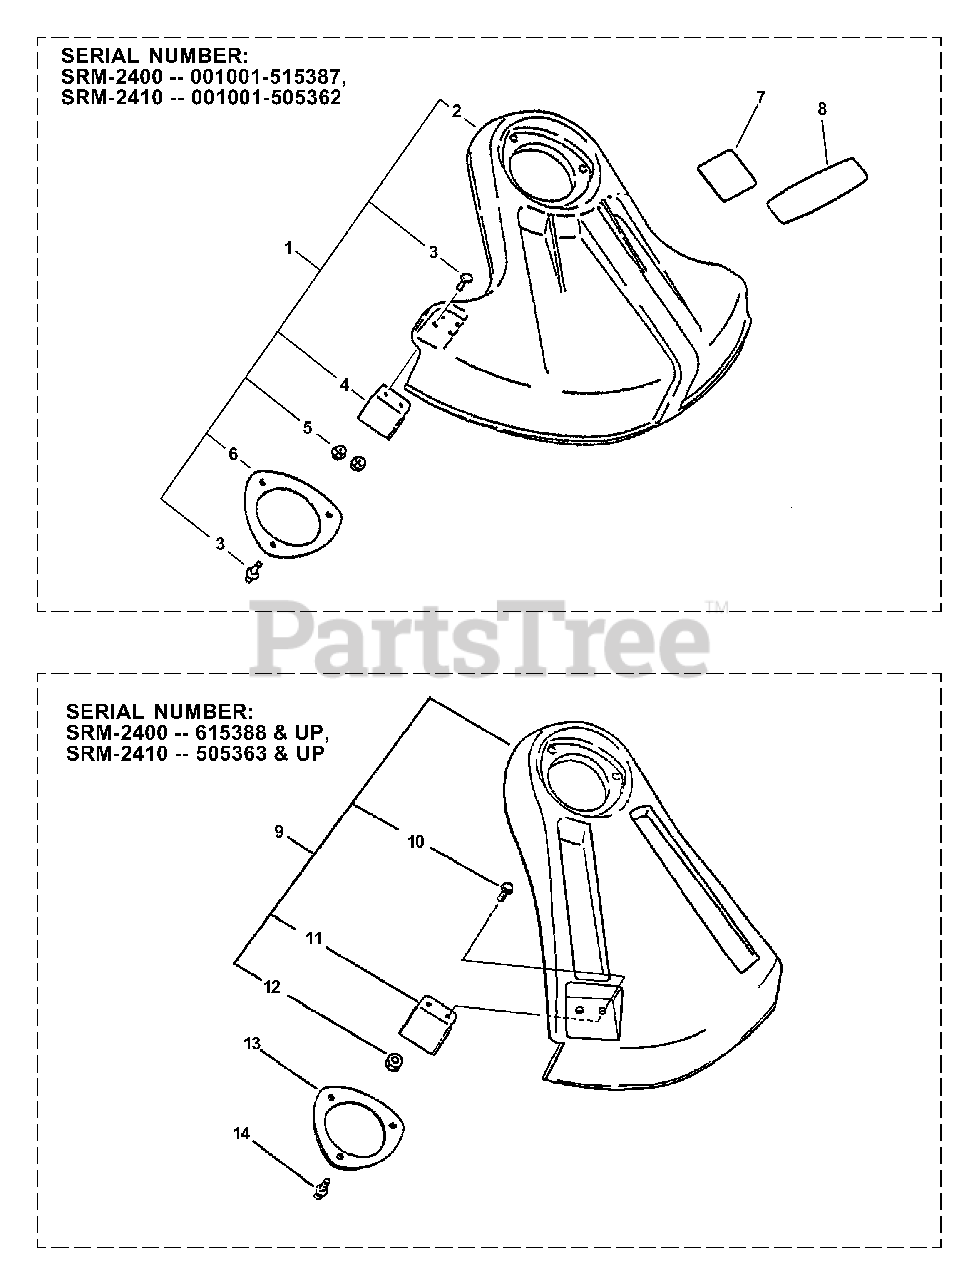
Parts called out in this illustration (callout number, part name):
1	DEBRIS SHIELD ASSY
2	SHIELD, DEBRIS
3	SCREW 5×16
4	CUTTER, LINE
5	NUT M5
6	PLATE, SHIELD Ø49.5 MM
7	LABEL, CAUTION
8	LABEL, ECHO
9	DEBRIS SHIELD KIT
10	SCREW 5×16
11	CUTTER, LINE
12	NUT M5
13	PLATE, SHIELD Ø49.5 MM
14	SCREW 5×16
